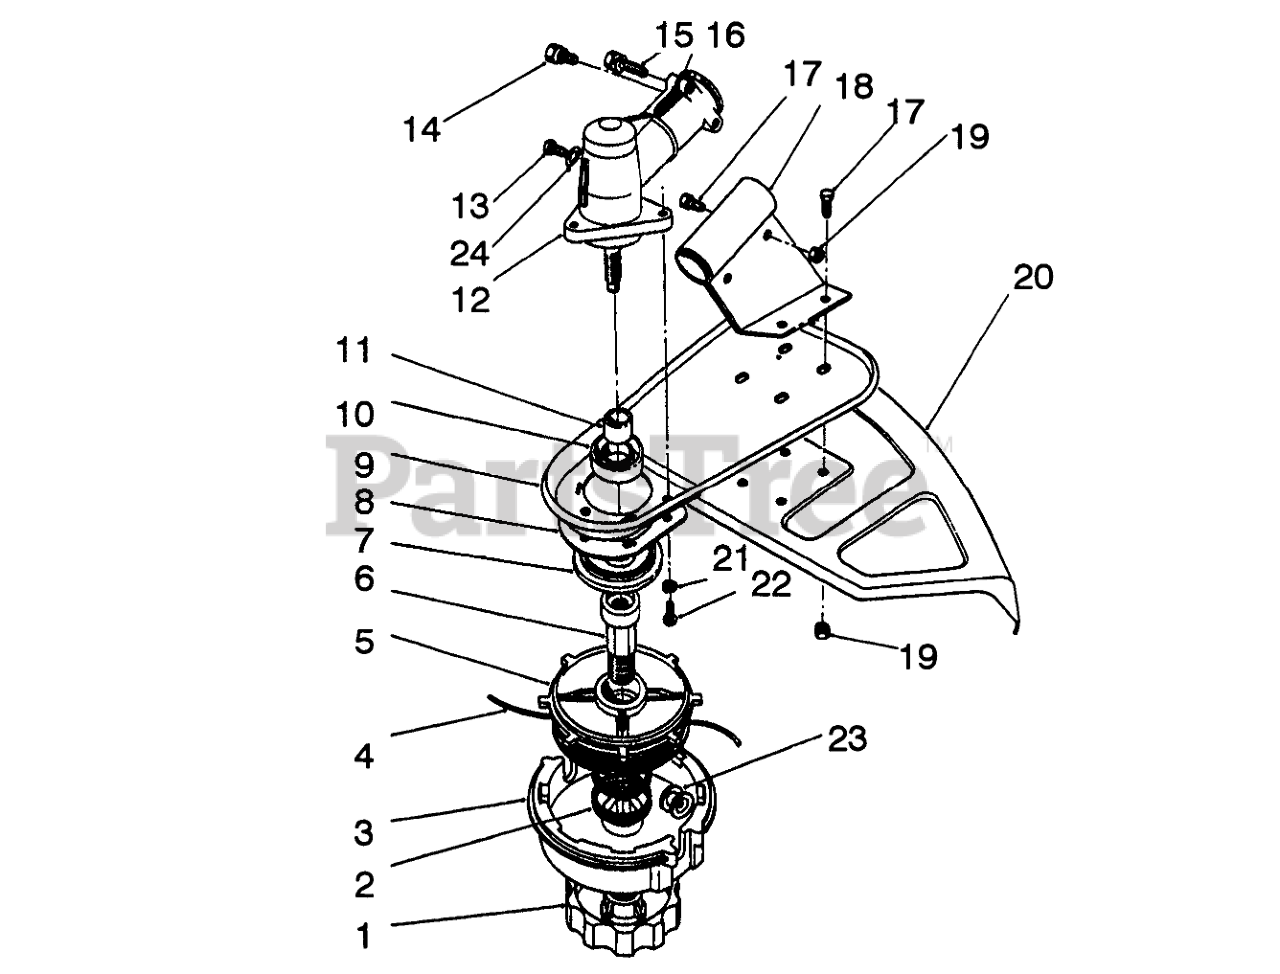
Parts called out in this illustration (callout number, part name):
1	LH KNOB(SERVICE ONLY)
2	SPRING (SERVICE)
3	SPOOL HSG (SERVICE ONLY
5	INNER SPOOL(SERV ONLY)
6	SHAFT (SERVICE ONLY)
7	DUST CAP F/W
8	GRASS WRAP GUARD
9	SHIELD SUPPORT R
10	OIL SEAL
11	SPLINED SLEEVE
12	Gear Box Assembly (Incl.Ref.#10,11,13-16 & 24)
13	HHMS SCREW
14	HHMS SCREW
15	HHMS SCREW
16	WASHER
17	SCREW-SHH
18	SHIELD BRKT
19	NUT-LOCK, NI
20	GRASS SHIELD R
21	LOCKWASHER
22	SCREW
23	EYELET(SERVICE)
24	GASKET
